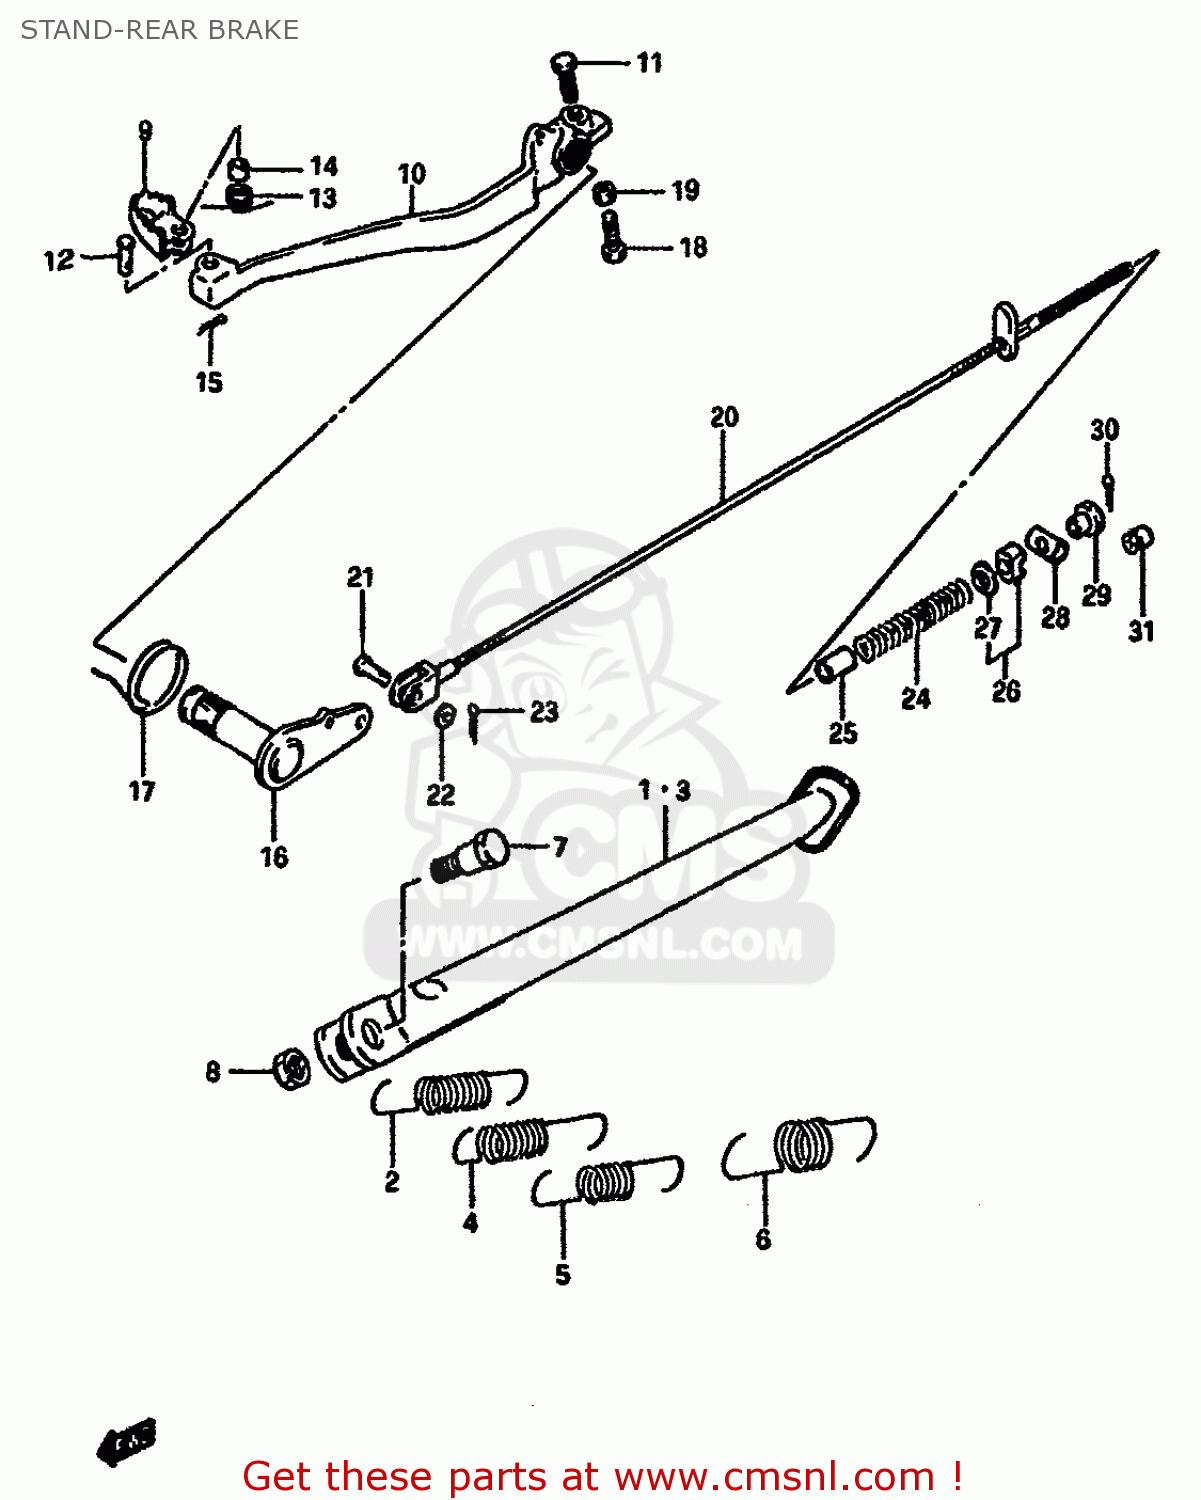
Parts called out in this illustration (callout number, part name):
1	STAND,SIDE
2	SPRING
3	STAND, PROP (BLUE)
4	SPRING
5	SPRING
6	SPRING
7	BOLT L:30
8	NUT
9	PEDAL,BRAKE
10	ARM,BRAKE PEDAL
11	BOLT
12	PIN
13	SPRING
14	SPACER(9.2X9X6.5)
15	PIN
16	ARM,BRAKE PEDAL ROD
17	SPRING
18	BOLT(6X23)
19	NUT 6MM
20	CABLE,RR BRAKE
21	PIN(L:17.5)
22	WASHER, LOWER
23	PIN
24	SPRING
25	CUSHION,FR GRILLE,UPPER
26	CUSHION
27	WASHER
28	PIN,BRAKE CABLE ADJUSTER
29	NUT (6MM)
30	PIN
31	CAP
